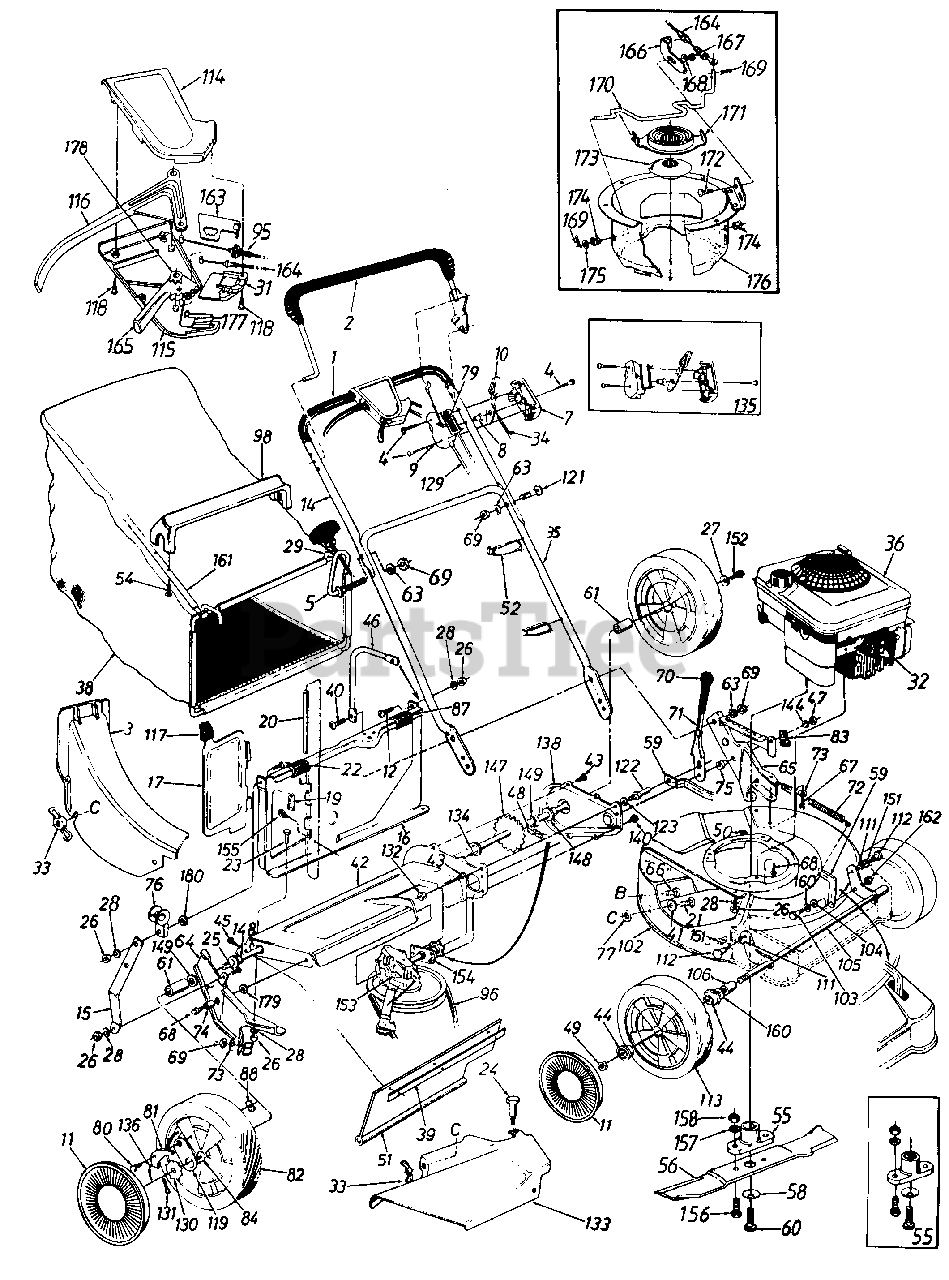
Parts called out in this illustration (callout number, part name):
1	Foam Grip-2 Req'd.
2	Control Handle Ass'y.-L.H.
3	Rear Discharge Chute Ass'y.
4	Truss Mach. Scr. #12 x 1.50" Lg.
5	Rope Guide Bolt
7	Control Panel Half
8	Control Disc Pin
9	Clutch Panel Half
10	Throttle Control Lever
11	Hub Cap
12	Truss Mach. Scr. 1/4-20 x .62" Lg.
14	Upper Handle-Painted
20	Pivot Pin
21	Carriage Bolt 1/4-20 x .62"
22	Truss Mach. Scr. 1/4-20 x 3/4" Lg.
23	Hex Bolt 1/4-20 x .50" Lg.
24	Shoulder Bolt .312 Dia. x .18 Lg.-Special
25	Hex Bolt 1/4-20 x .62" Lg.*
26	Hex Nut 1/4-20 Thd.
27	Bell-Wash. 1/4" I.D.
28	L-Wash. 1/4" I.D.
31	S.P. Control Cover
32	Spark Plug Insulator
33	Wing Nutw/Washer
34	Throttle Control Wire 61"
35	Lower Handle-Painted
36	Engine
38	Grass Bag
39	Retaining Strip
40	Truss Mach. Scr. 5/16-18 x .75" Lg.
41	Fl-Wash. .344" I.D. x .62"
44	Flange Ball Bearing 1/2" I.D.
45	Hex AB-Tap Scr. 1/4 x .62"
46	Catcher Panel Support Arm
47	Hex Patch L-Nut 3/8-24 Thd.
48	#48 Chain .500" Pitch x 30 Links
49	Hex L-Nut 1/2-20 Thd.
51	Rear Flap 3.75" x 17.30" Lg.
52	Cable Tie
54	Hex AB Scr. #12 x 1.25" Lg.
55	Blade Adapter Kit
56	21" Blade
58	Bell-Wash. .46" I.D.
59	HeightAdj. Connecting Arm
60	Hex Bolt 7/16-20 x 1.5" Lg. (Grade 5)
61	Spacer .513" I.D. x .703" O.D. x .69" Lg.
63	L-Wash. 5/16" I.D.*
64	R.H. Handle Wheel Brkt. Ass'y.
65	L.H. Handle Wheel Brkt. Ass'y.
66	Carriage Bolt 5/16-18 x .62"*
67	Hex Wash. Hd. B-Tap Scr. 5/1 6-1 8
68	Hex Wash. Hd. TT-Tap Scr. 3/8-1 6
69	Hex Nut 5/16-18 Thd.*
71	Height Adj. Lever
72	Extension Spring .75" O.D. x8" Lg.
73	Bell-Wash. 5/16" I.D.
74	Spacer
75	Shld. Spacer .500" Dia.
76	Rope Guide
77	Bolt Retainer 1/4 x .50" O.D.
79	Control Label
80	Shld. Scr. .342" Dia. x .268
81	Pawl
82	Wheel Ass'y. Comp.
83	Clamp
84	Bearing 1/2" I.D.
87	Panel Clip
88	Flat Weld Nut 1/4-20 Thd.
95	S.P. Cable
96	"V"-Belt
98	Bag Handle
102	638/N 21" Deck Ass'y.
103	Shld. Bolt .5" Dia. x .295
104	Bell-Wash. .515" I.D. x 1.0" O.D.
105	FrontAxle Ass'y.
106	Sleeve .526" I.D. x .690" O.D. x .880" Lg.
111	Intern. L-Wash. 3/8 I.D.*
112	Shld. Bolt .575" Dia. x .42
113	Wheel Ass'y. Comp.
114	Self-Propelled Control Cover
115	Self-Propelled Control Cover
116	Control Lever
117	Door Grip
118	Fl-"C"-Sunk Hd. Tap Scr. #10 x .75" Lg.
119	Pawl Plate
121	Curved Carr. Bolt 5/16-18 x 1.38" Lg.
122	Shld. Pin 3/8-24 x 1.43" Lg.
123	L-Wash. 3/8" I.D.*
129	Control Cable 46" Lg.
130	Ratchet Wheel 1.62" O.D.
131	Cotter Pin 1/8" Dia. x 1.00" Lg.
132	Hex Jam Nut 3/8-24 Thd.
133	Side Chute Deflector Ass'y.
134	Hex Flange Bearing
135	Kit-Control Housing Comp.
136	Spring-Nylon
144	Fl-Wash. .385" I.D. x .87"
147	Rear Shaft Ass'y. 21.94" Lg.
148	Hex Flange Bearing .506" I.D. Plastic
149	Fl-Wash. .531" I.D. x .930"
151	Flanged Nyliner Brg.
152	Hex Bolt 1/4-20 x .62" Lg. (Grade 5)
153	Transmission Comp.
155	Hex B-Tap Scr. #10 x .38
156	Hex Scr. 3/8-24 x 1.0" Lg.
157	L-Wash. 3/8" I.D.
158	Hex Nut 3/8-24 Thd.
160	Fl-Wash. .51 " I.D. x .75" O.D.
162	Hex Jam Nut 3/8-16 Thd.
163	6-Speed Rack Cable Brkt.
164	Spd. Control Cable-50" Lg.
165	6-Spd. Shift Lever
168	Bell-Wash. .265" I.D. x .75" O.D.
169	Cot-Pin 3/32" Dia. x .75" Lg.
170	Shift Rod
171	Movable Pulley Half Ass'y.
172	Carr. Bolt 1/4-20 x .50" Lg.
173	Splined Pulley Half
174	Flanged Bushing
175	Fl-Wash. .328" I.D. x .68" O.D.
176	Cable Mtg. Brkt. Ass'y.
177	Shift Lever Spring
178	3-Tooth Rack Gear Insert
179	Fl-Wash. .383" I.D. x 1" O.D.
180	Fl-Wash. .285" I.D. x 1.25" O.D.
